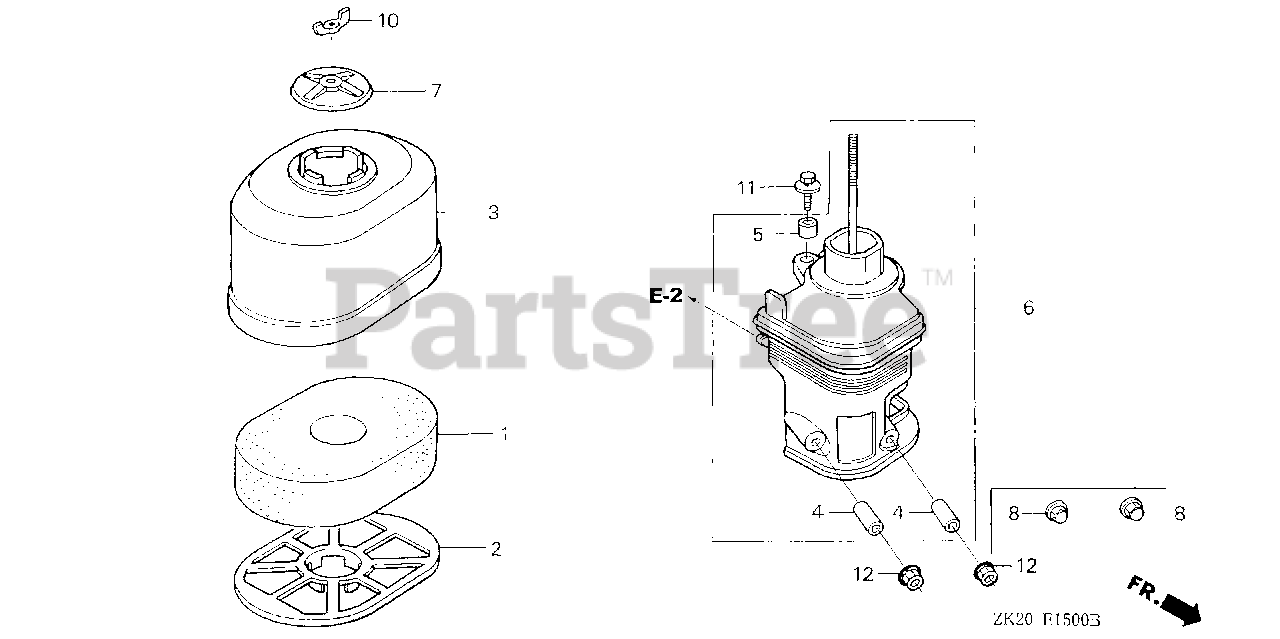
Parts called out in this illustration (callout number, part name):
1	ELEMENT, AIR CLEANER (SEMI-DRY)
2	GRID, AIR CLEANER
3	COVER, AIR CLEANER (SEMI-DRY)
4	COLLAR, AIR CLEANER
5	COLLAR B, AIR CLEANER
6	ELBOW, AIR CLEANER
7	CAP, AIR CLEANER
10	NUT, TOOL BOX SETTING
11	BOLT-WASHER (6X20)
12	NUT, FLANGE (6MM)
